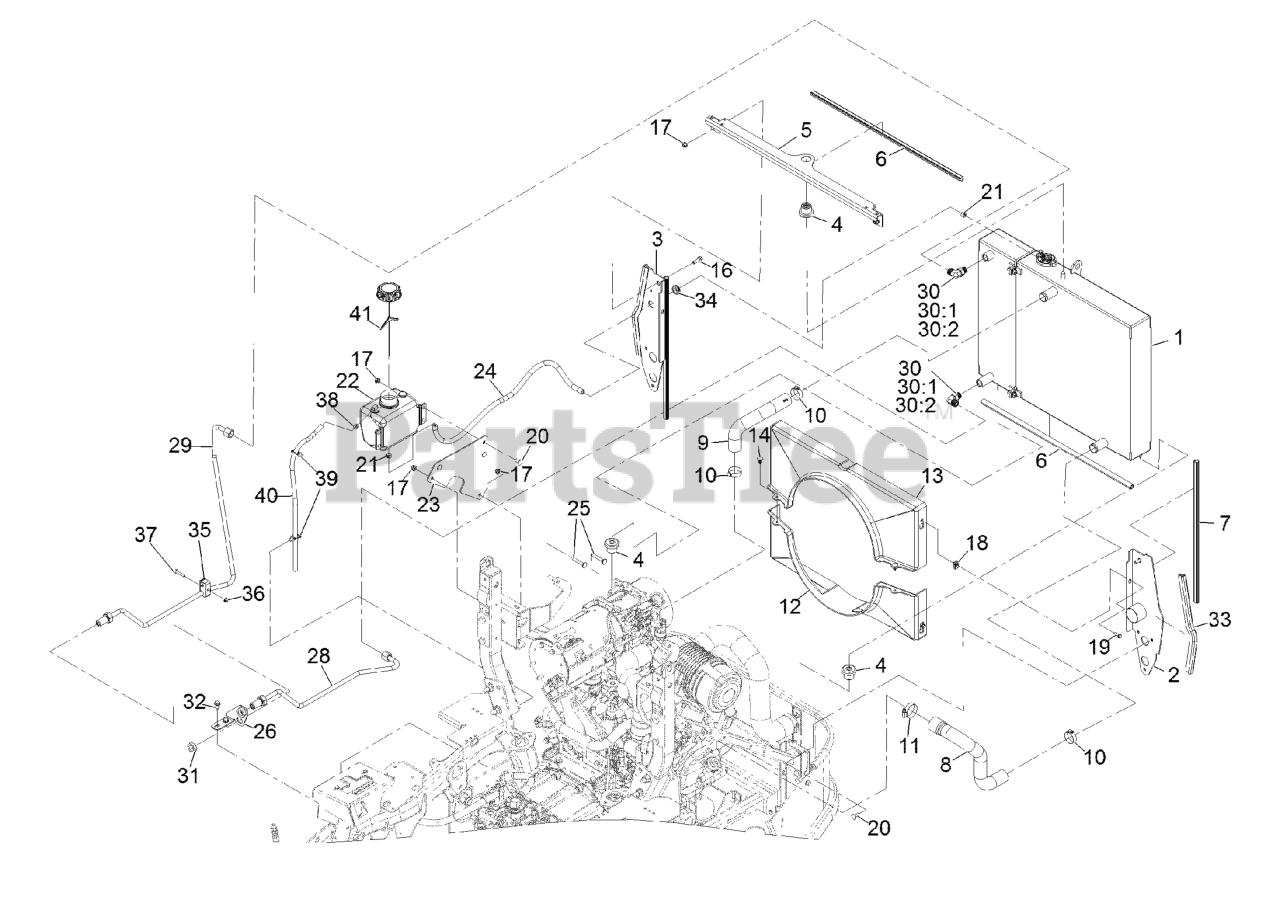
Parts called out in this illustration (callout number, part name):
1	COOLING ASM
2	SUPPORT-RADIATOR, LH
3	SUPPORT-RADIATOR, RH
4	MOUNT-ISOLATOR
5	BRACKET-COOLING, TOP
6	SEAL-BULB
7	SEAL-BULB
8	HOSE-RADIATOR, LOWER
9	HOSE-RADIATOR, UPPER
10	CLAMP-HOSE
11	CLAMP-HOSE
12	SHROUD-BOTTOM
13	SHROUD-TOP
14	PLUG-PLASTIC
16	SCREW-HHF
17	NUT-HF, NI
19	SCREW-HWH
20	SCREW-CARR
21	CLAMP-HOSE
22	TANK-OVERFLOW, W/CAP
23	BRACKET-BOTTLE
25	BOLT-CARR
26	BRACKET-BULKHEAD
28	HYDRAULIC TUBE ASM
29	HYDRAULIC TUBE ASM
30	FITTING-ELBOW, 90 DEG
30:1	O-RING
30:2	O-RING
31	NUT-BULKHEAD
32	Screw-HWH 5/16-18 X 3/4 Tf
33	SEAL-BULB
34	GROMMET
35	CLAMP-TWIN
37	SCREW-HH
38	CLAMP-HOSE
39	CLIP-TIE
40	HOSE-FUEL
41	CAP-W/TETHER
